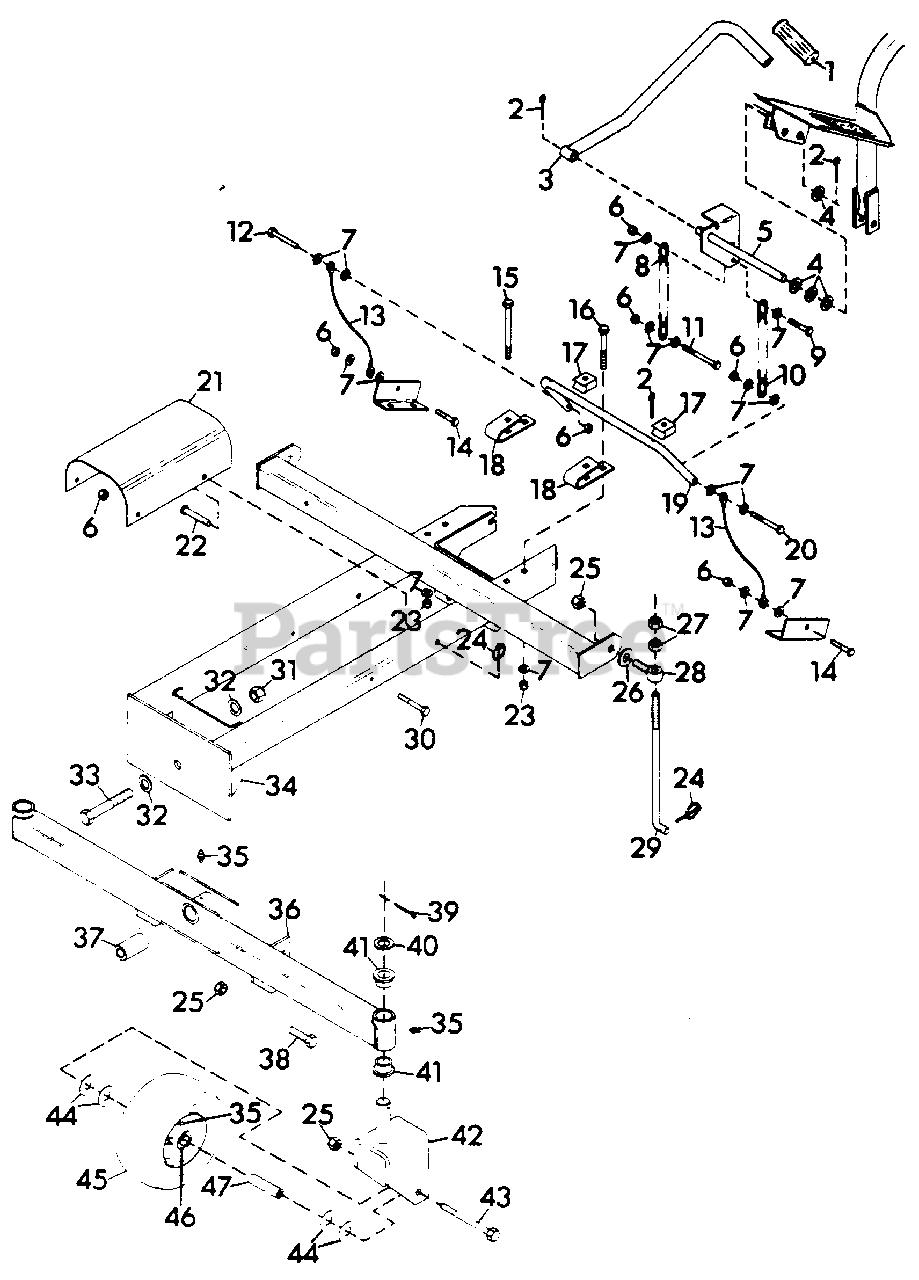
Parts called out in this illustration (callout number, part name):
1	GRIP
2	PIN, COTTER .12X1.25
3	WELDMENT, LIFT LEVER
4	WASHER, FLAT .656X1.250X.100
5	WELDMENT, LIFT BRACKET
6	NUT, LOCK 5/16-18
7	WASHER, FLAT .406X.812X.065
8	CHAIN, LIFT(8 LINKS)
9	BOLT, HEX 5/16-18X1.25
10	CHAIN, LIFT(7 LINKS)
11	BOLT, HEX 5/16-18X3.25
12	BOLT, HEX 5/16-18X1.75
13	CABLE, LIFT
14	BOLT, HEX 5/16-18X1.00
15	BOLT, HEX 3/8-16X4.00
16	BOLT, HEX 3/8-16X3.00
17	STOP, NYLON
18	BRACKET, AXLE SUPPORT
19	ARM, PIVOT
20	BOLT, HEX 5/16-18X2.00
21	GUARD, PTO SHAFT
22	PIN, CLEVIS
23	NUT, LOCK 3/8-16
24	PIN, KLIK
25	NUT, LOCK 1/2-13
26	WASHER, FLAT .500X1.250X.083
27	NUT, JAM 1/2-13 HEX
28	BOLT, EYE
29	ROD, HEIGHT ADJUSTMENT
30	BOLT, HEX 5/16-18X2.50
31	NUT, LOCK 3/4-10
32	WASHER, FLAT .812X1.469X.130
33	BOLT, HEX 3/4-10X4.50
34	WELDMENT, MOWER FRAME
35	FITTING, LUBE 1/4-28
36	AXLE
37	TUBE, PIVOT
38	BOLT, HEX 1/2-13X1.375
39	PIN, COTTER .187X1.625
40	RACE, BEARING THRUST
41	BUSHING, PIVOT
42	WELDMENT, CASTER FORK
43	BOLT, HEX 1/2-13X5.00
44	WASHER, FLAT .531X1.250X.100
45	WHEEL, GAUGE
46	BEARING, GAUGE WHEEL
47	BUSHING, WHEEL
